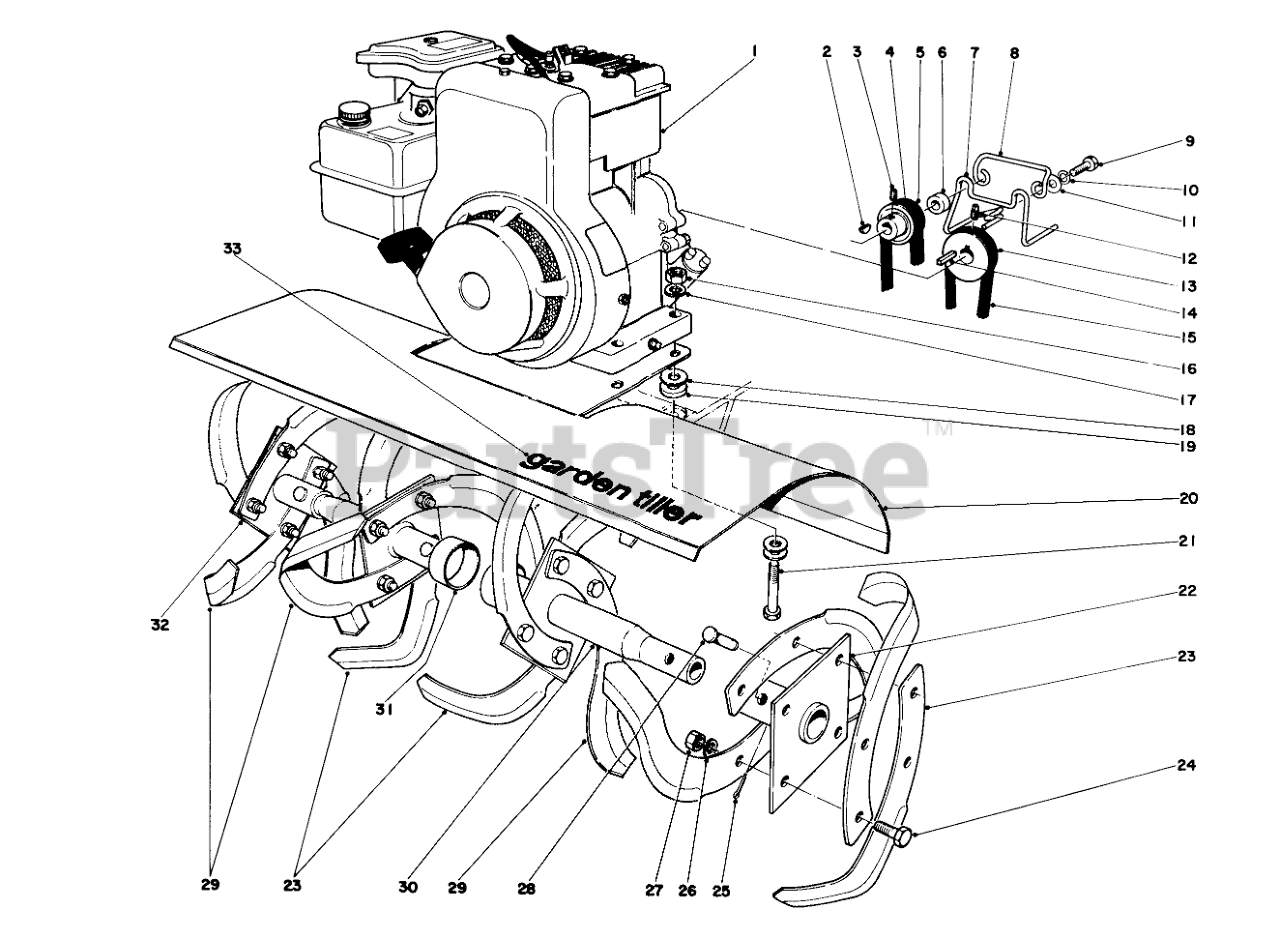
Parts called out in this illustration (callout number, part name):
1	Engine
2	KEY-WOODRUFF
3	SCREW-SET
5	PULLEY
6	SPACER
7	Upper Belt Guide
8	Cover Latch
9	SCREW-HH
10	WASHER-LOCK
11	WASHER-FLAT
12	SCREW-SET, HSH
13	Engine Pulley
14	KEY-SQUARE
16	NUT-HEX
17	WASHER-LOCK
18	WASHER-FLAT
19	WASHER-FLAT
20	Shield
21	SCREW-HH
22	Axle L.H.Outer
23	RH TINE
24	SCREW-HH
25	PIN-COTTER
26	WASHER-LOCK
27	NUT-HEX
28	TINE PIN
29	LH TINE
30	Axle L.H. Inner
31	Axle R.H. Inner
32	Axle R.H. Outer
33	Decal
